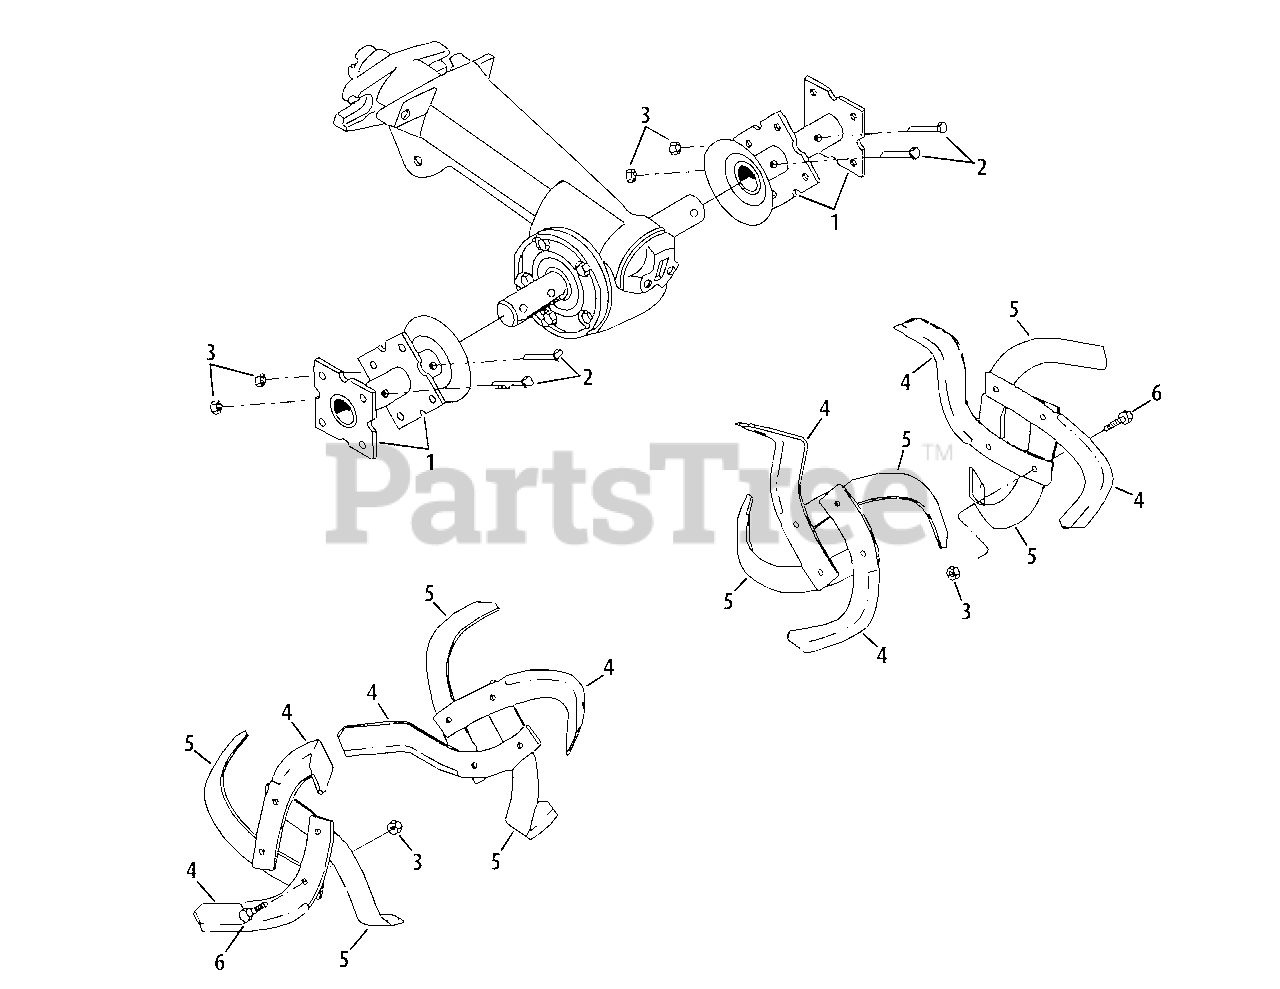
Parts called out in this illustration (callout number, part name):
2	Hex Bolt, 3/8"-16 x 2"
3	Hex Locknut, 3/8"-16
4	Bolo Tine Left
5	Bolo Tine Right
6	Hex Head Screw, 3/8"-16 x 1"
